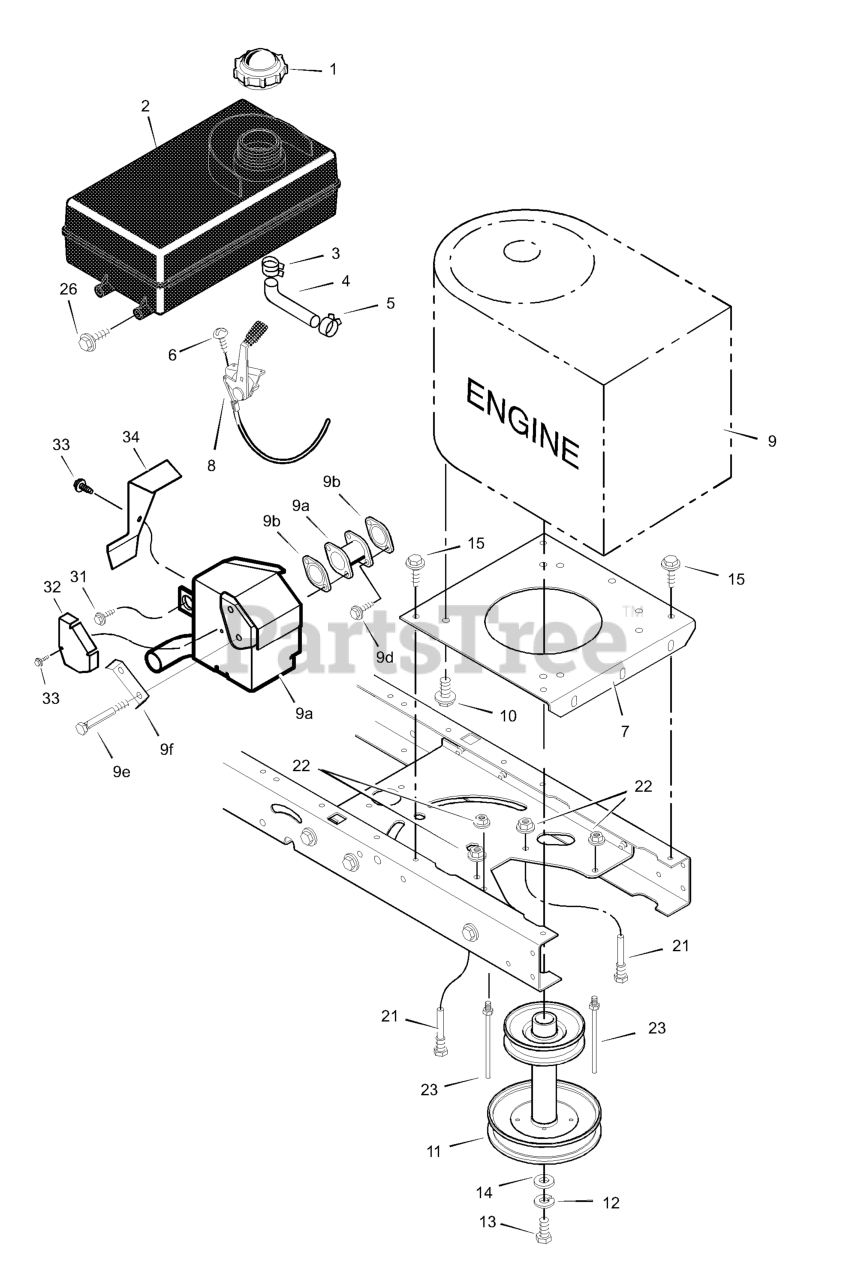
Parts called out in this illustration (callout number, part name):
1	Fuel Cap
2	Fuel Tank
3	Hose Clamp
4	Fuel Line (Must cut to length)
5	Hose Clamp
7	Plate, Engine
8	Throttle Control
9	Engine
9A	Muffler and Heat Shield
9B	GASKET, Exhaust
9C	Adapter, Muffler
9D	Screw, Adapter
9E	Bolt, Muffler
9F	Lock, Screw
10	Bolt, Engine Mount
11	STACK PULLEY ASSEMBLY
12	Lockwasher
13	Bolt, Hex
21	Guide, Belt
22	Nut, Flange
23	Guide, Belt
32	Shield, Heat -Cover
34	Shield, Top
